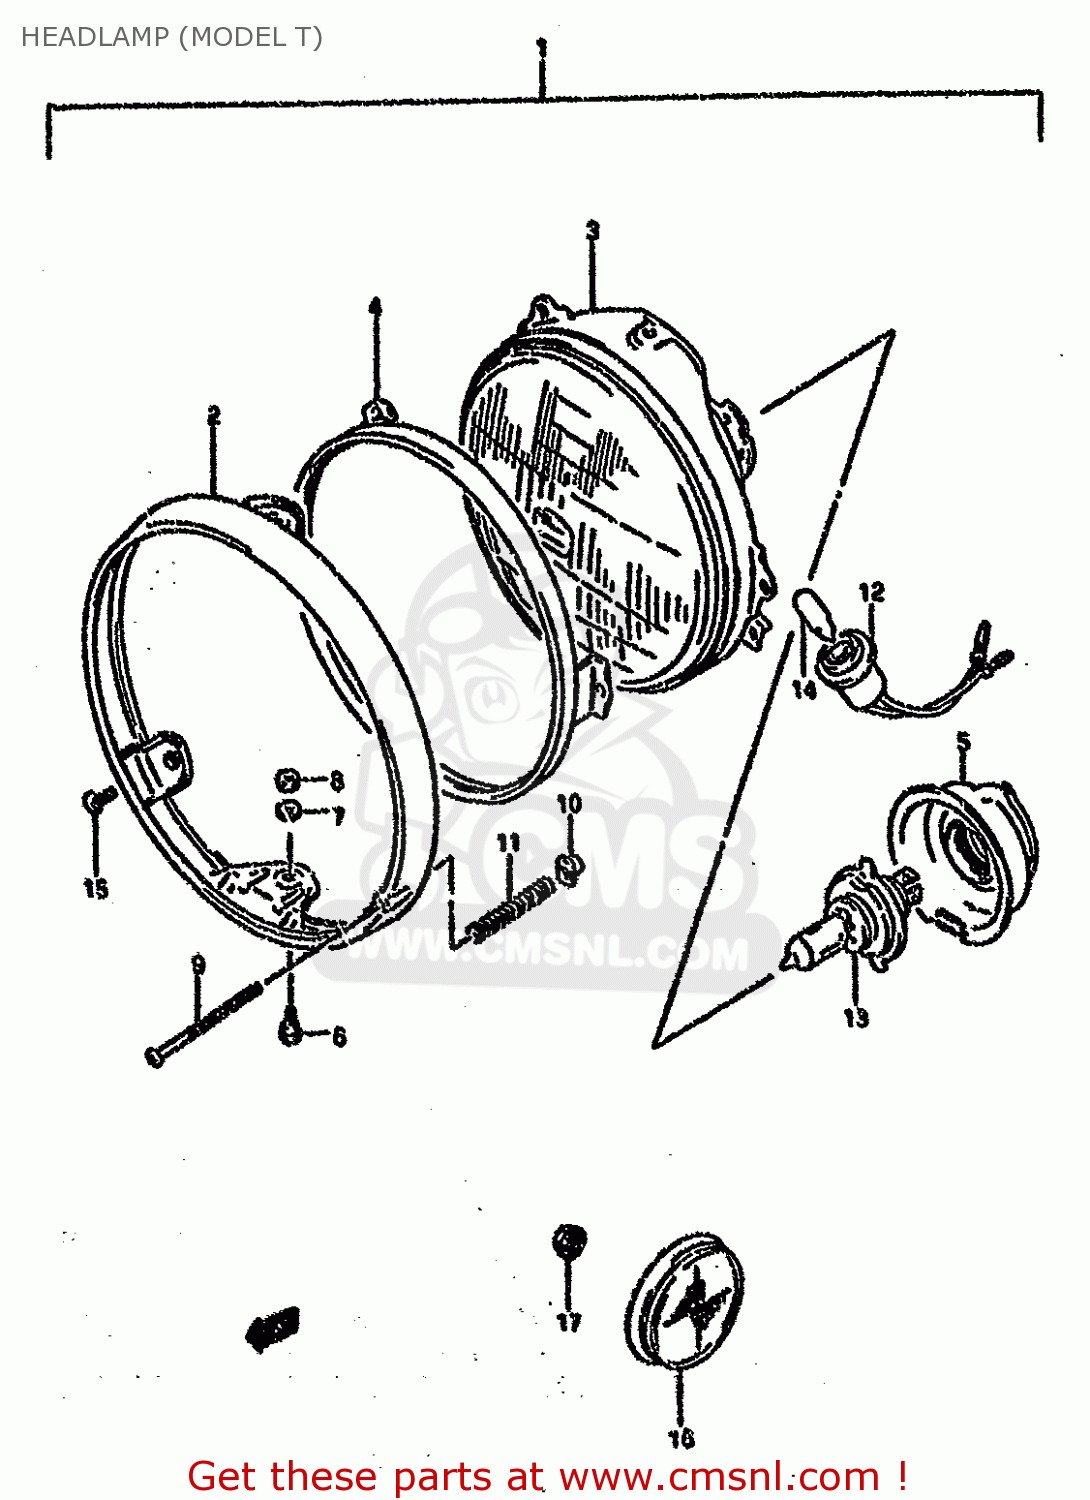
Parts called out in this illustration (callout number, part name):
1	HEADLAMP ASSY
2	RIM,HEADLAMP
3	LAMP UNIT
4	RING
5	COVER,SOCKET
6	H/LAMP LENS UNIT FITING SCRE
7	WASHER,LOCK
8	NUT
9	SCREW
10	NUT
11	SPRING,ADJUSTING
12	SOCKET
13	BULB(12V60/55W,H4)
14	BULB(12V4W)
15	SCREW
16	REFLECTOR,REFLEX FR
17	NUT
22	SCREW
23	REFLECTOR,REFLEX FR
24	NUT
